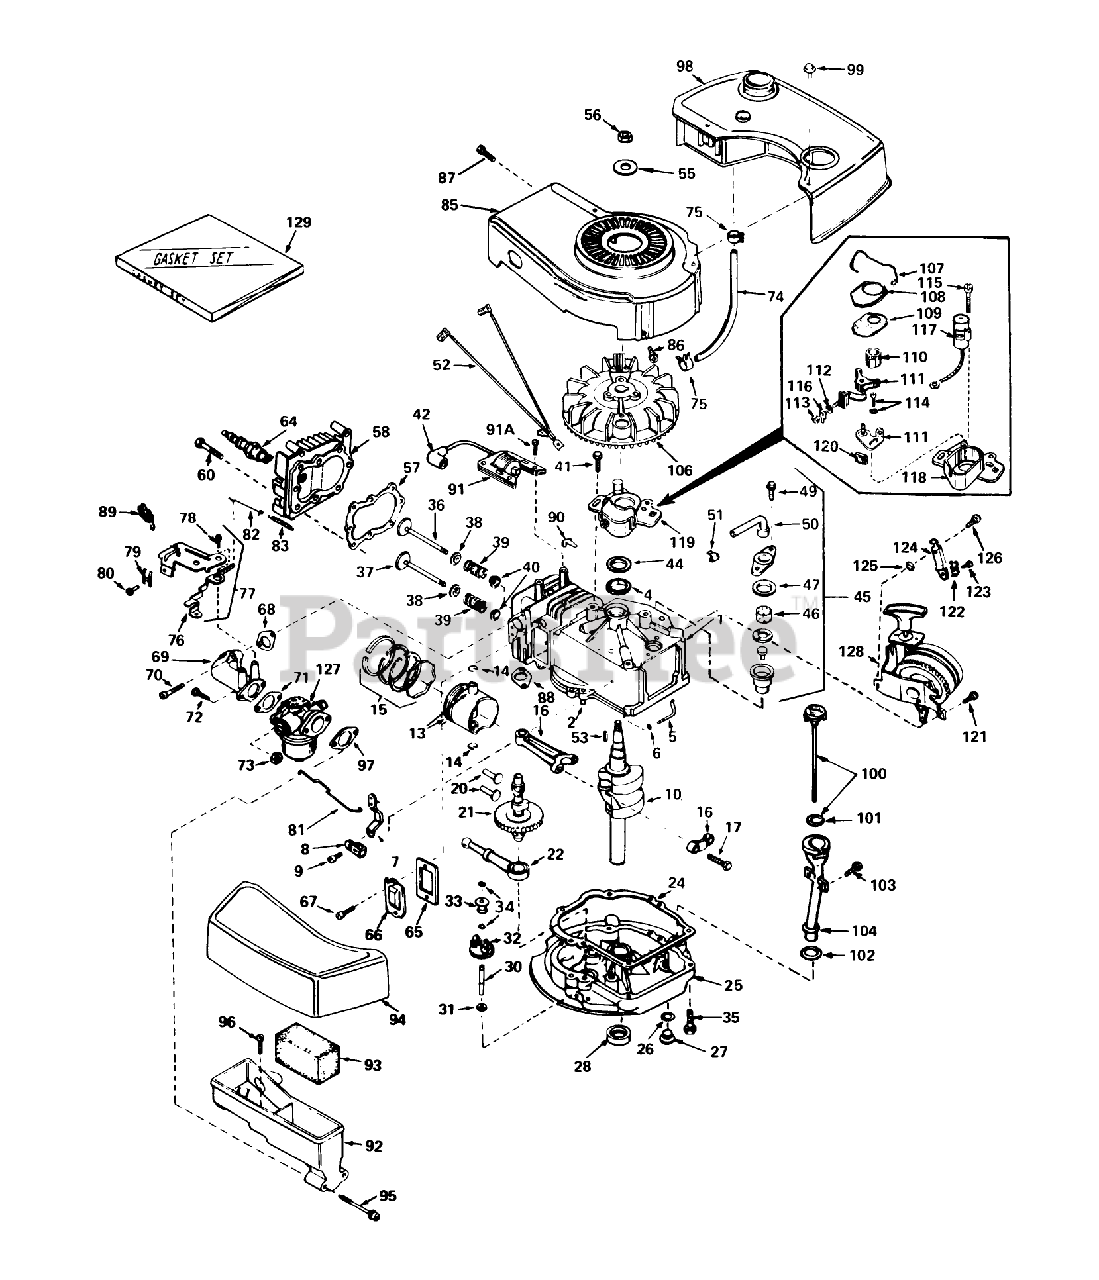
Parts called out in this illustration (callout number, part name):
1	Cyiinder Assy. (Incl. Ref. #2, 4 105)
2	Pin-Dowel
4	Seal-Oil
5	Rod, Governor (Incl. No. 36)
6	Washer-Flat
7	Governor Lever
8	Clamp-Lever, Governor
9	Screw
10	Crankshaft
13	Piston, Pin Ring Assy. (Incl.Ref. #14 15)(Std.)
13	Piston, Pin Ring Assy. (Incl. #14 15)(.010 oversize)
13	Piston, Pin Ring Assy. (Incl.Ref. #14 15) (.020 oversize)
14	Ring-Retaining, Piston Pin
15	Ring Set Piston (Std.)
15	Ring Set Piston (.010 Oversize)
15	Ring Set Piston (.020 Oversize)
16	Rod Assy., Connecting (Incl. Ref. #17)
17	Bolt-Rod, Connecting
20	Lifter-Valve
21	Camshaft(Mech.Comp. Release)
22	Oil Pump ASM
24	Gasket, Mounting
25	Flange Assy., Mounting (Incl. Ref. #26thru 30)
26	Gasket-Oil Drain
27	Plug Oil Drain
28	Seal Oil
30	Shaft-Governor
31	Washer-Flat
32	Governor Gear ASM
33	Spool-Governor
34	Ring-Retaining
35	Screw (1/4-20 x 1-1/4)
36	Valve, Intake (Incl. Ref. #38, 39 40) (Std.)
36	Valve, Exhaust (1/32" Oversize) (Incl. Nos. 8, 9 10)
37	Valve, Exhaust (Standard) (Incl. Nos. 8, 9 10)
37	Valve, Exhaust (1/32" Oversize) (Incl. Nos. 8, 9 10)
38	Cap-Upper Valve Spring
39	Spring-Valve
40	Cap-Valve, Spring
41	Screw, Hex Hd. Sems
42	Cover-Spark Plug
44	Gasket Stator
45	Breather Assy. (Incl. Ref. #46, 47, 49, 50 51 )
46	Element-Breather
47	Gasket-Breather
49	Screw, Hex Hd. w/Conical
50	Tube, Breaker
51	Clip, Breather
52	Wire Ground
53	682488 LB GRASS HI-
55	Washer-Belleville
56	Nut-Flywheel
57	63573 GIL 42 SNWTHW
58	Head-Cylinder
60	Screw (5/16-18x1-1/2)
64	Plug, Spark (J17LM or equiv.)
64	Plug, Spark (Champion RCJ-8)
65	Gasket-Breather
66	Cover-Valve
67	Screw
68	Gasket, Intake
69	Pipe, Intake
70	Screw (1/4-20 x 1)
71	Gasket-Carburetor
73	Nut and Lock Washer (1/4-28)
74	Line-Fuel
75	Clamp-Line, Fuel
76	Lever Control
77	Control Assy., Speed (Incl. Nos, 76, 78 89)
78	Screw, Hex Washer Hd Shoulder Self-Tap
79	Conduit
80	Screw (10-32 x 3/8)
81	Link-Throttle
82	Link Governor Spring
83	Spring Governor
85	Housing Blower
86	Screw
87	Screw (10-24 x 9/16)
88	Gasket Exhaust
89	Terminal
90	Clip-Wire
91	Lamination Coil Assy. (Incl. No. 42)
91A	Screw
92	Body Air Cleaner
93	Filer, Air
94	Cove, Air Cleaner
95	Screw Fil Hd.
96	Screw, Hex Hd.
97	Gasket-Air Cleaner
98	Tank, Fuel
99	Screw (10-32 x 35/64)
100	Dipstick, Oil (Incl. Ref. #101)(Twist Lock)
101	O-Ring
102	Gasket
103	Screw (10-32 x 1/2)
104	Tube-Oil Fill
106	FIywheel
107	Spring Breaker Box
108	Cover-Dust
109	Gasket-Dust Cover
110	Cam-Breaker
111	Breaker Assy.
112	Washer
113	DECAL
114	Breaker Screw
115	Condenser Screw
116	Terminal, Ground
117	Condenser
118	Stator Plate
119	Stator Plate Assy. (incl. Nos. 107, 111 thru 118 120)
120	Felt,Cam Wiper
121	Screw (1/4-20 x 1/2)
122	Conduit
123	Screw (10-32 x 3/8)
124	Bracker
125	Washer
126	Screw (1/4-20 X 5/8)
127	Carburetor (Incl. Ref. #71 )
128	Starter
129	53024/VAR.16HP O/P
